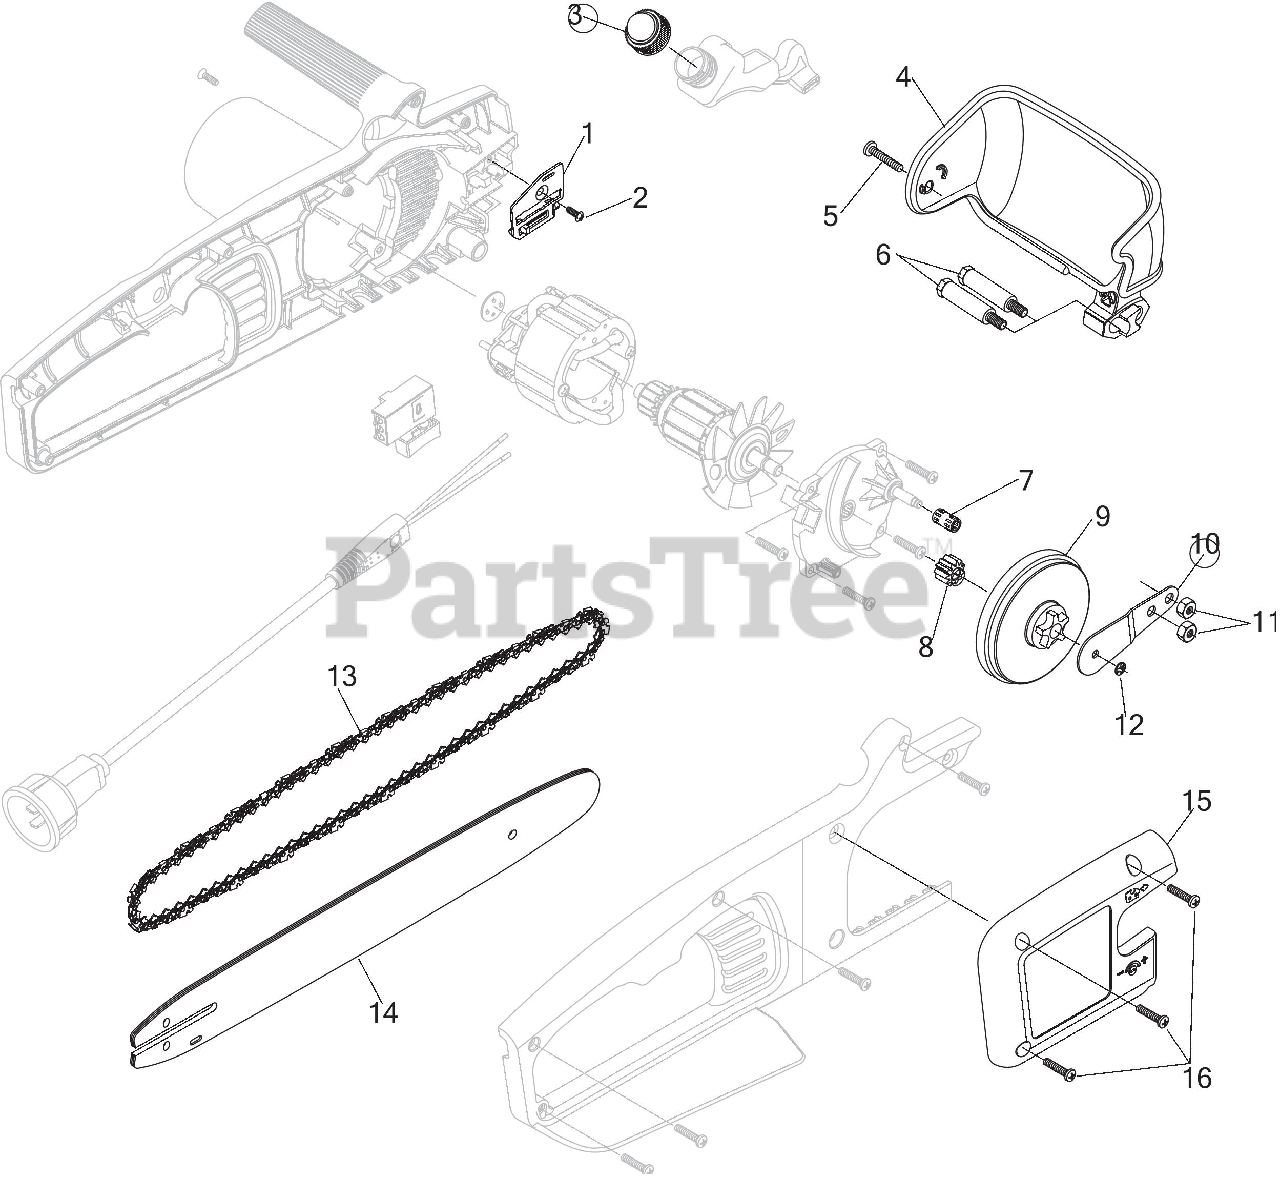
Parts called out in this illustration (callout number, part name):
1	ADJUST PLATE
2	SCREW #6 x .50
3	OIL CAP/BULB ASSEMBLY
5	SCREW #10 x 1.25
6	SHOULDER BOLT
7	ROLLER BEARING
8	DRIVE GEAR
9	SPROCKET/GEAR ASSEMBLY
10	SPROCKET SUPPORT
12	E-RING
13	CHAIN 10"
14	POLESAW BAR 10"
15	SPROCKET COVER
16	SCREW 8-18X7/8
